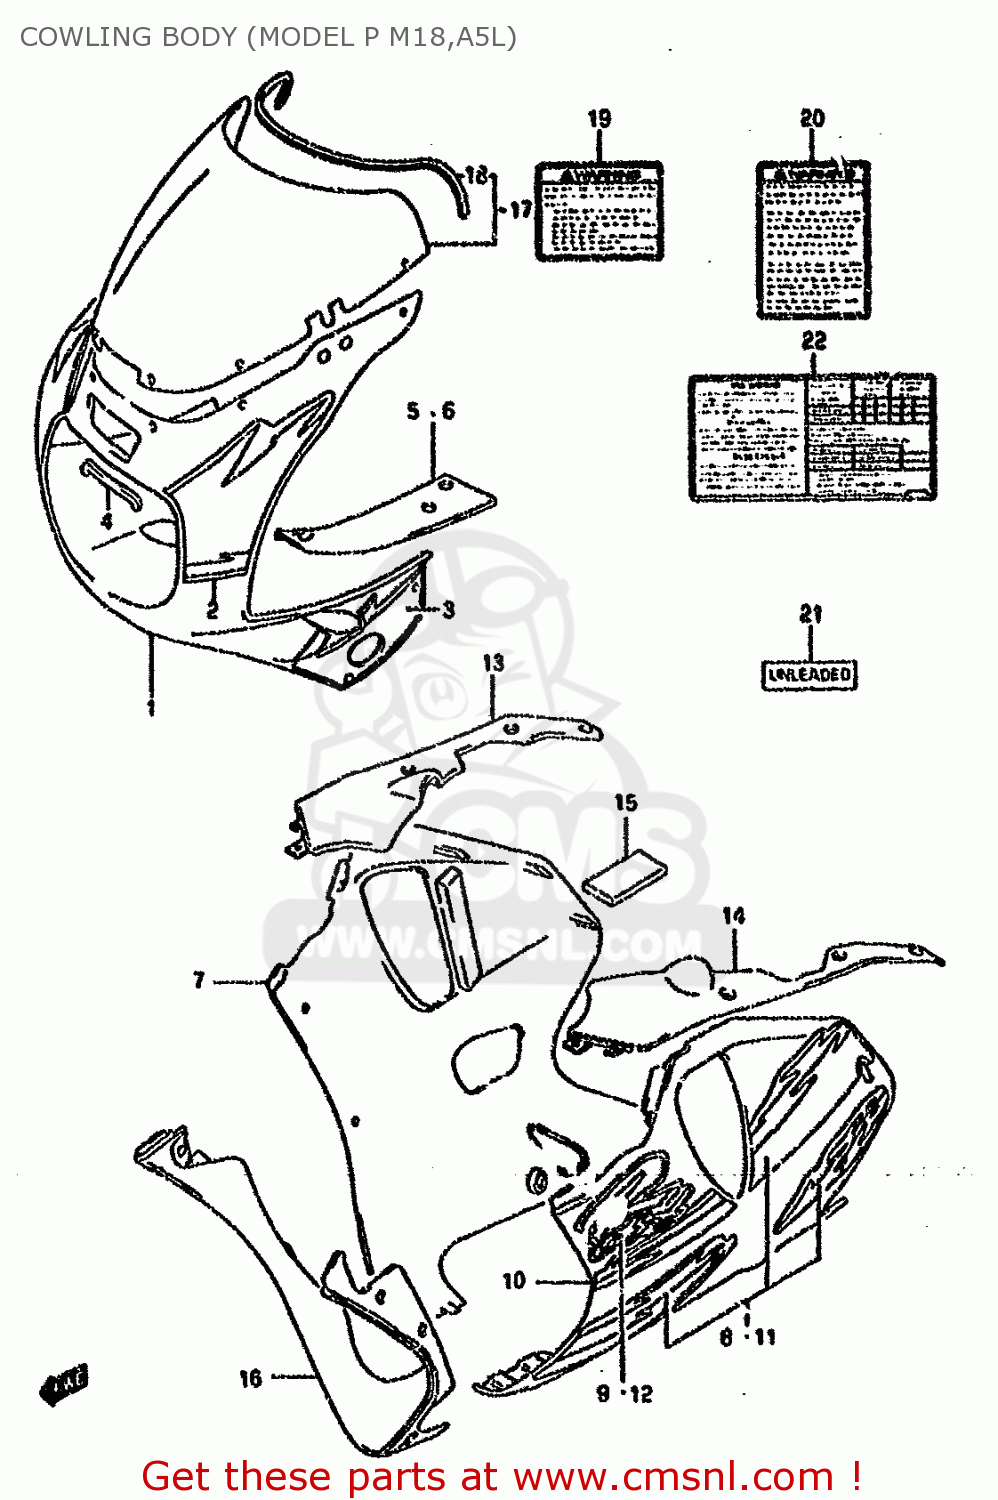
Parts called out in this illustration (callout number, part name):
1	COWLING ASSY,BODY
2	TAPE SET,COWL BODY FR
3	TAPE SET,COWLING BODY
4	CUSHION,FR POSITION LAMP
5	PANEL,UPR,R
6	PANEL,UPR,L
7	COWLING ASSY,UNDER,R
8	TAPE SET,COWL UNDER,R
9	EMBLEM,COWLING,UNDER
10	COWLING ASSY,UNDER,L
11	TAPE SET,COWLING,UNDER
12	EMBLEM,COWLING,UNDER
13	PANEL,LWR,R
14	PANEL,LWR,L
15	CUSHION,PANEL
16	COWLING,UNDER CTR
17	WINDSCREEN SET
18	MOLDING
19	LABEL, WARNING SAFETY
20	LABEL (WARNING SCREEN)
21	LABEL,CAUTION
22	LABEL,TIRE AIR PRESSURE
